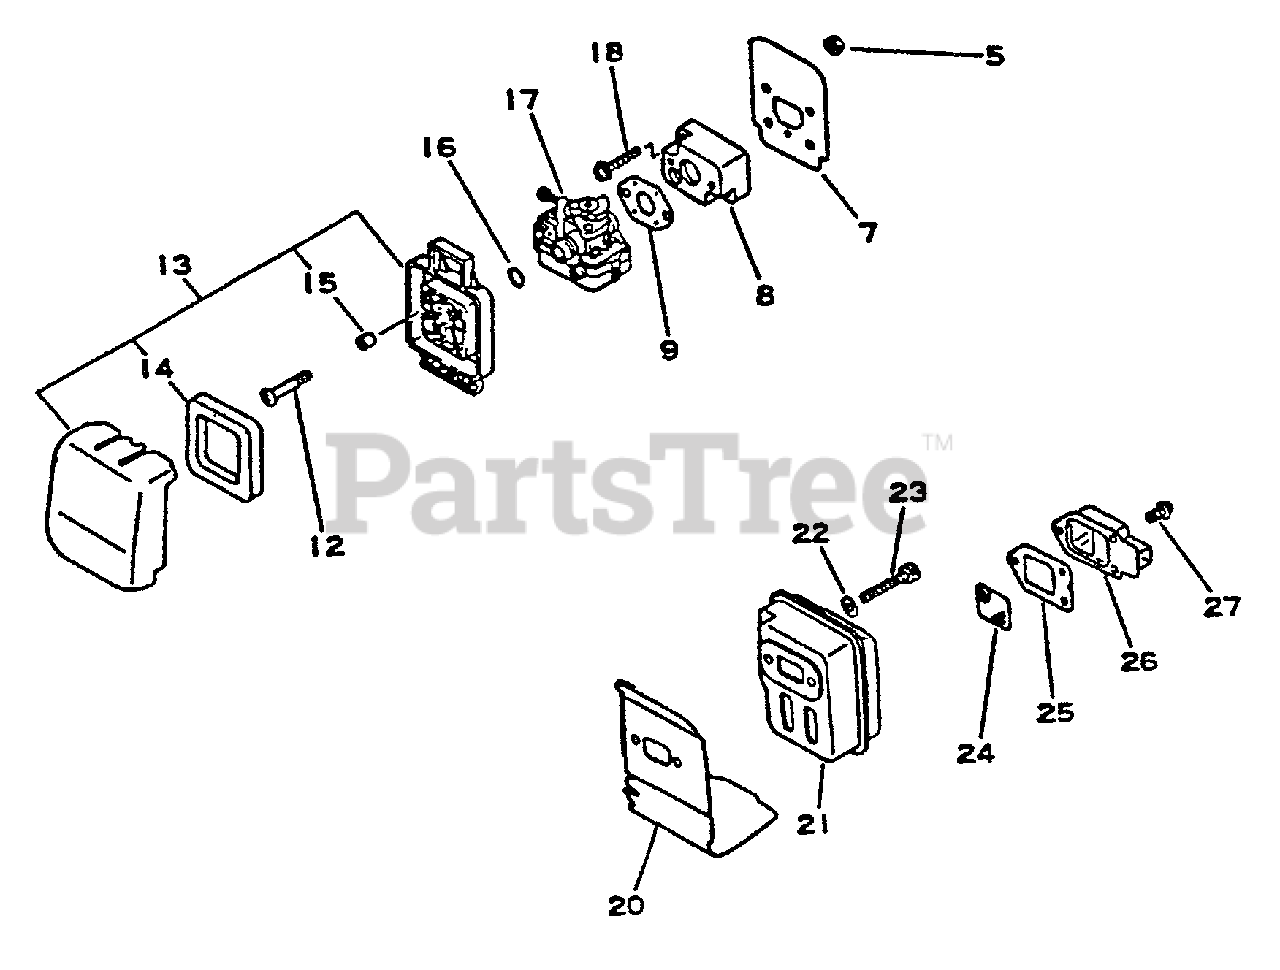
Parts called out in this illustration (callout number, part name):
7	SHIELD, INTAKE
8	INSULATOR, INTAKE
9	GASKET, INTAKE
12	SCREW - 5X64
13	AIR CLEANER ASSY
14	FILTER, AIR
15	SLEEVE
16	O-RING - 15
17	CARBURETOR WYL-1
18	SCREW - 5X22
20	GASKET, EXHAUST
21	MUFFLER
22	WASHER - 5
23	SCREW - 5X55
24	SCREEN, SPARK ARRESTOR
25	GASKET, EXHAUST
26	GUIDE, EXHAUST - OUTER
27	SCREW - 4X10
